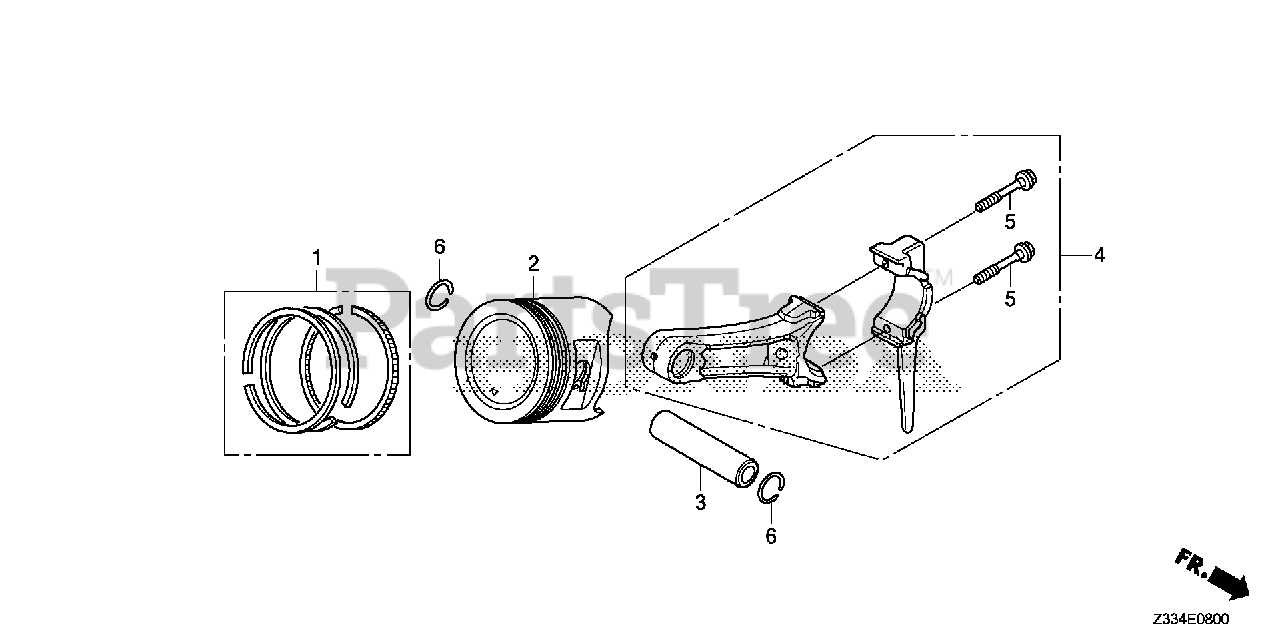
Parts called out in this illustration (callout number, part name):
1	RING SET, PISTON (STD) (TEIKOKU)
1	RING SET, PISTON (0.25) (TEIKOKU)
1	RING SET, PISTON (0.50) (TEIKOKU)
1	RING SET, PISTON (0.75) (TEIKOKU)
2	PISTON (STD)
2	PISTON (0.25)
2	PISTON (0.50)
2	PISTON (0.75)
3	PIN, PISTON
4	ROD ASSY., CONNECTING (0.25 LOWER SIZE)
4	ROD ASSY., CONNECTING (STD)
5	BOLT, CONNECTING ROD
6	CLIP, PISTON PIN (18MM)
